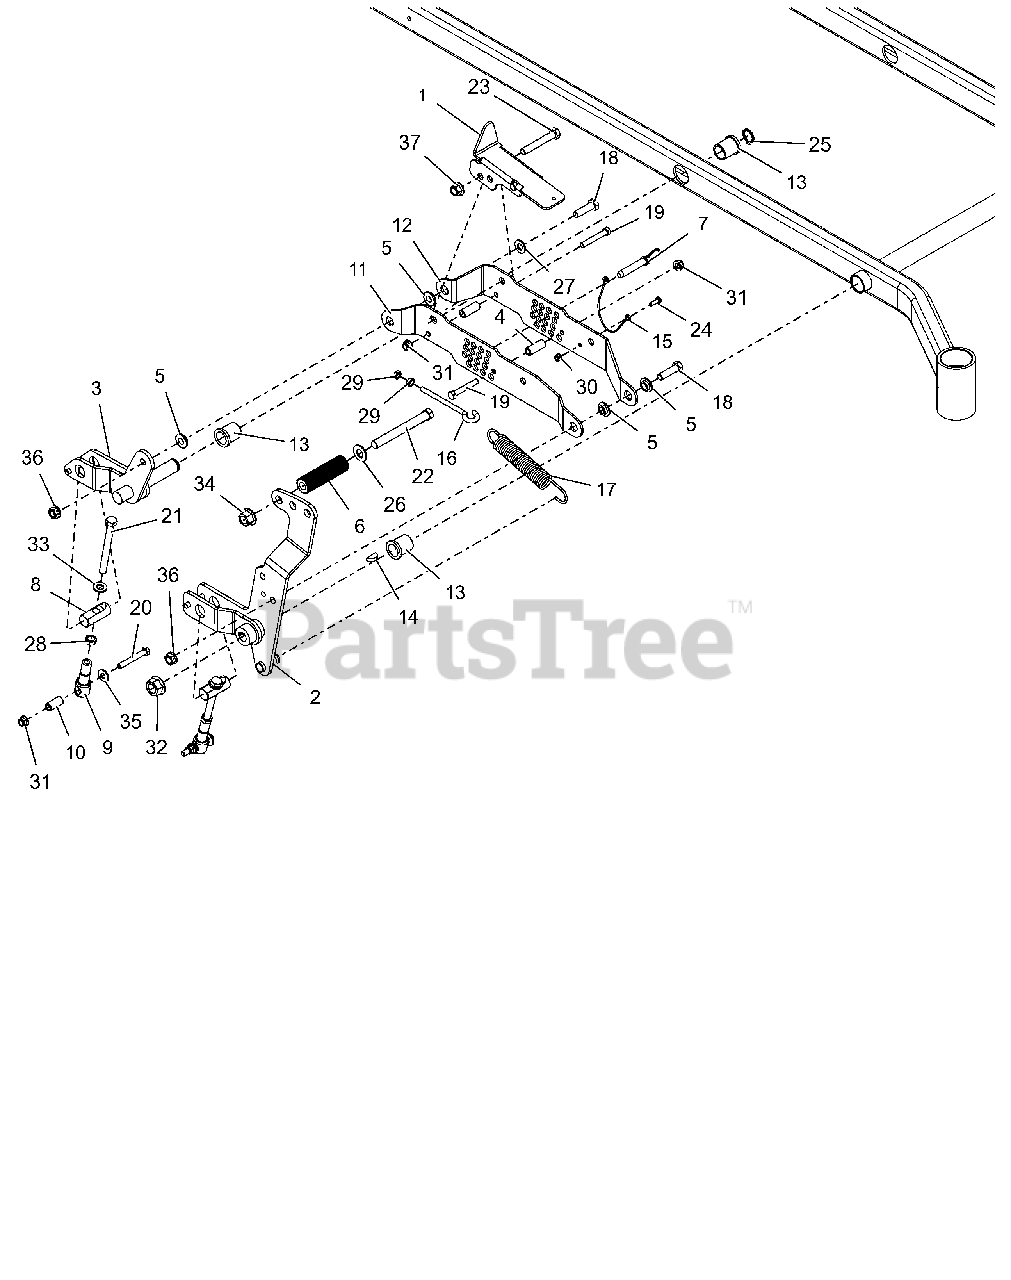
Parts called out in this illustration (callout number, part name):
1	MECHANICAL LOCK-UP WMT - BLACK
2	FRT RH DECK LIFT ARM WMT- LF
3	REAR RH DECK LIFT ARM WMT- LF
4	SPACER, .375 X .625 X 1.54
5	BSHG-FLG .515X.750X.310X1.120
6	ROD, FOOT PEDAL (BLACK)
7	PIN, .50 X 2.00 USABLE LG BALL
8	PIN, DECK LIFT
9	LINK, DECK LIFT FORMED
10	SPACER, DECK LEVELING
11	RH OTBRRD LIFT/CUT HT BRKT-BLK
12	RH INBRD LIFT/CUT HT BRKT-BLK
13	BSHG-FLG 1.00X1.25X1.50X1.50
14	KEY-WDRF .25X1.00 HRD #15
15	CABLE, 12.0 LANYARD, NYLON
16	BOLT,.38-16 X 4.25-.62 DIA EYE
17	SG-TENS .162X1.25X8.25 WLD 25
18	@BLT-HEX .50-13X1.75 GR5 YWZC
19	@BLT-HEX .38-16X2.50 GR5 YWZC
20	BLT-HEX .38-16X2.75 GR8 YWZC
21	BOLT, 1/2-13 X 5.0 2.5 THREAD
22	BLT, HEX .62-11X5.50 G5 FBP
23	@BLT-HEX .50-13X3.25 GR5 YWZC
24	@BLT-HEX .25-20X.75 GR5 YWZC
25	RG-RTNG-EXT 1.00X.078
26	WSHRFLT 5/8SAE CARBHARD FBP
27	WSHR,FLT .531X1.062X.095 ZCC
28	NUT-JAM .50-13 YWZC
29	NUT-HEX-JAM .375-16 YWZC
30	@NUT-LK-NYL-FLG .25-20 YWZC
31	@NUT-LK-NYL-FLG .38-16 YWZC
32	NUT-HEX-FLG-TPLK .75-10 YWZC
33	FLATWASHER 1/2 SAE HARD 15906
34	NUT,FLG-TOP LK .625-11 FBP
35	@WSHR-FL-STL.438X1.00X.083 YWZ
36	NUT-LK-CTR-FLG .50-13 YWZC
37	@NUT-LK-NYL-FLG .50-13 YWZC
